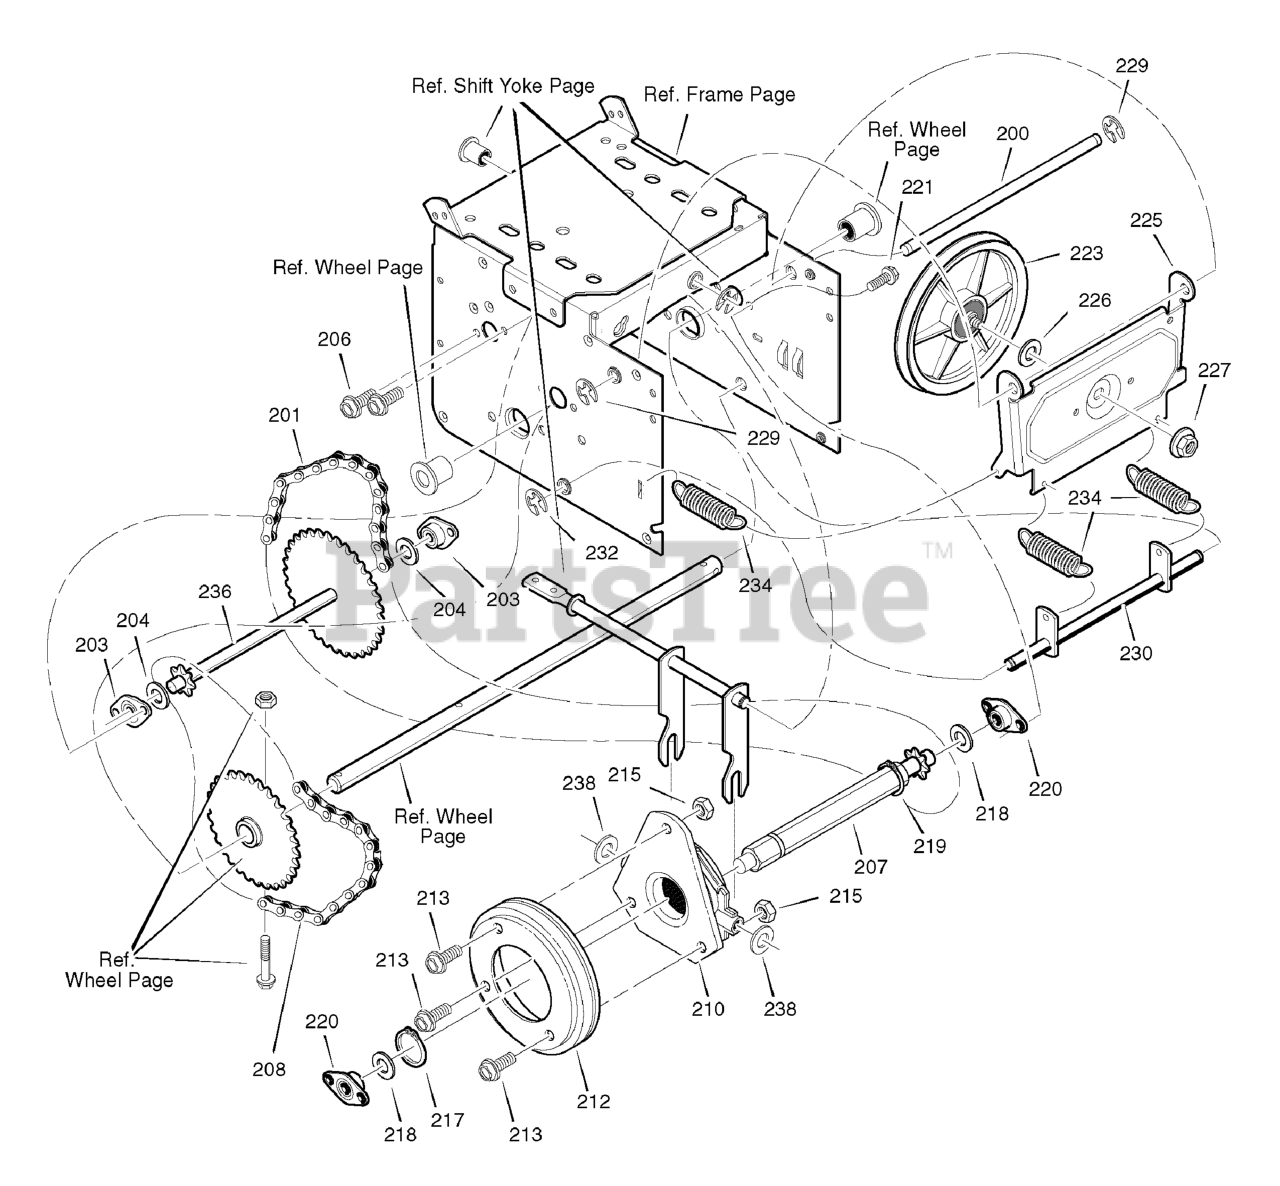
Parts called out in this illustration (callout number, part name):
200	AXLE, L.F. Swing Plate
201	CHAIN, Roller, #420 x 19
203	BEARING & RETAINER ASSEMBLY
206	SCREW, Tap, 5/16 - 18 x 1/2
207	HEX SHAFT ASSEMBLY
208	CHAIN, Roller, #420 x 18
210	BEARING, Trunion Clutch R.H.
212	WHEEL, Friction Disc
215	NUT, Hex Keps, 1/4 - 20
217	RING, Retainer
219	RING, Snap
220	BEARING & RETAINER ASSEMBLY
221	SCREW, Tap, 5/16 - 18 x 1/2
223	FRICTION PULLEY ASSEMBLY
225	PLATE, L.F. Swinging
226	SPACER, Friction Pulley
227	NUT, Flange Lock, 3/8 - 24
229	RETAINER, Ring
230	SPRING LINK ASSEMBLY, L.F
232	RETAINER, Ring
234	SPRING, Extension
236	SPROCKET
238	WASHER, Flat
